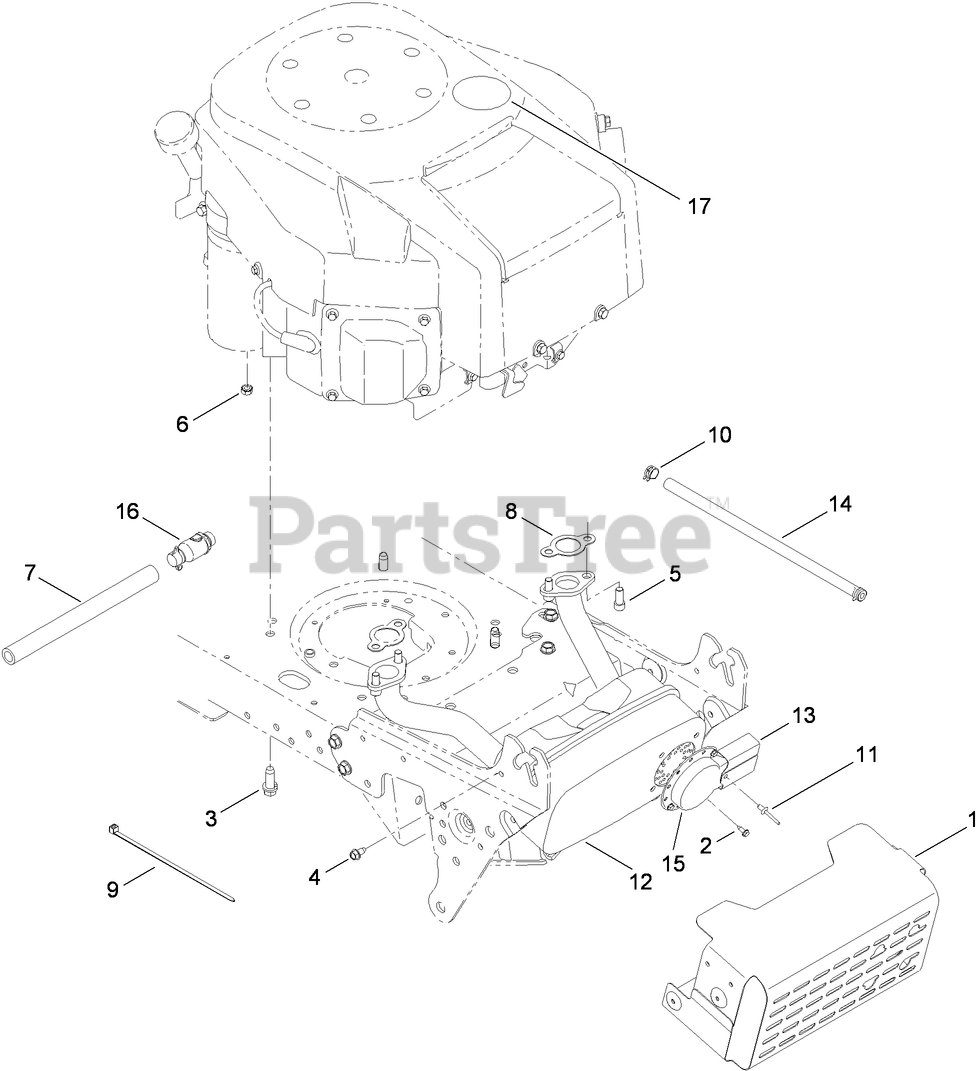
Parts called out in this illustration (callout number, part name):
1	SHIELD-MUFFLER
2	SCREW-HWHTF
3	SCREW-HH, TAP
4	SCREW-HWHTF
5	SCREW-HSH
6	NUT-SEMS
7	HOSE-DRAIN
8	GASKET-EXHAUST
9	TIE-CABLE
10	CLAMP-HOSE
11	RIVET-POP
12	MUFFLER-TWIN
13	DEFLECTOR-MUFFLER
14	HOSE-FUEL
15	DEFLECTOR-MUFFLER, LONG
16	DRAIN-OIL
17	DECAL-CHECK OIL
